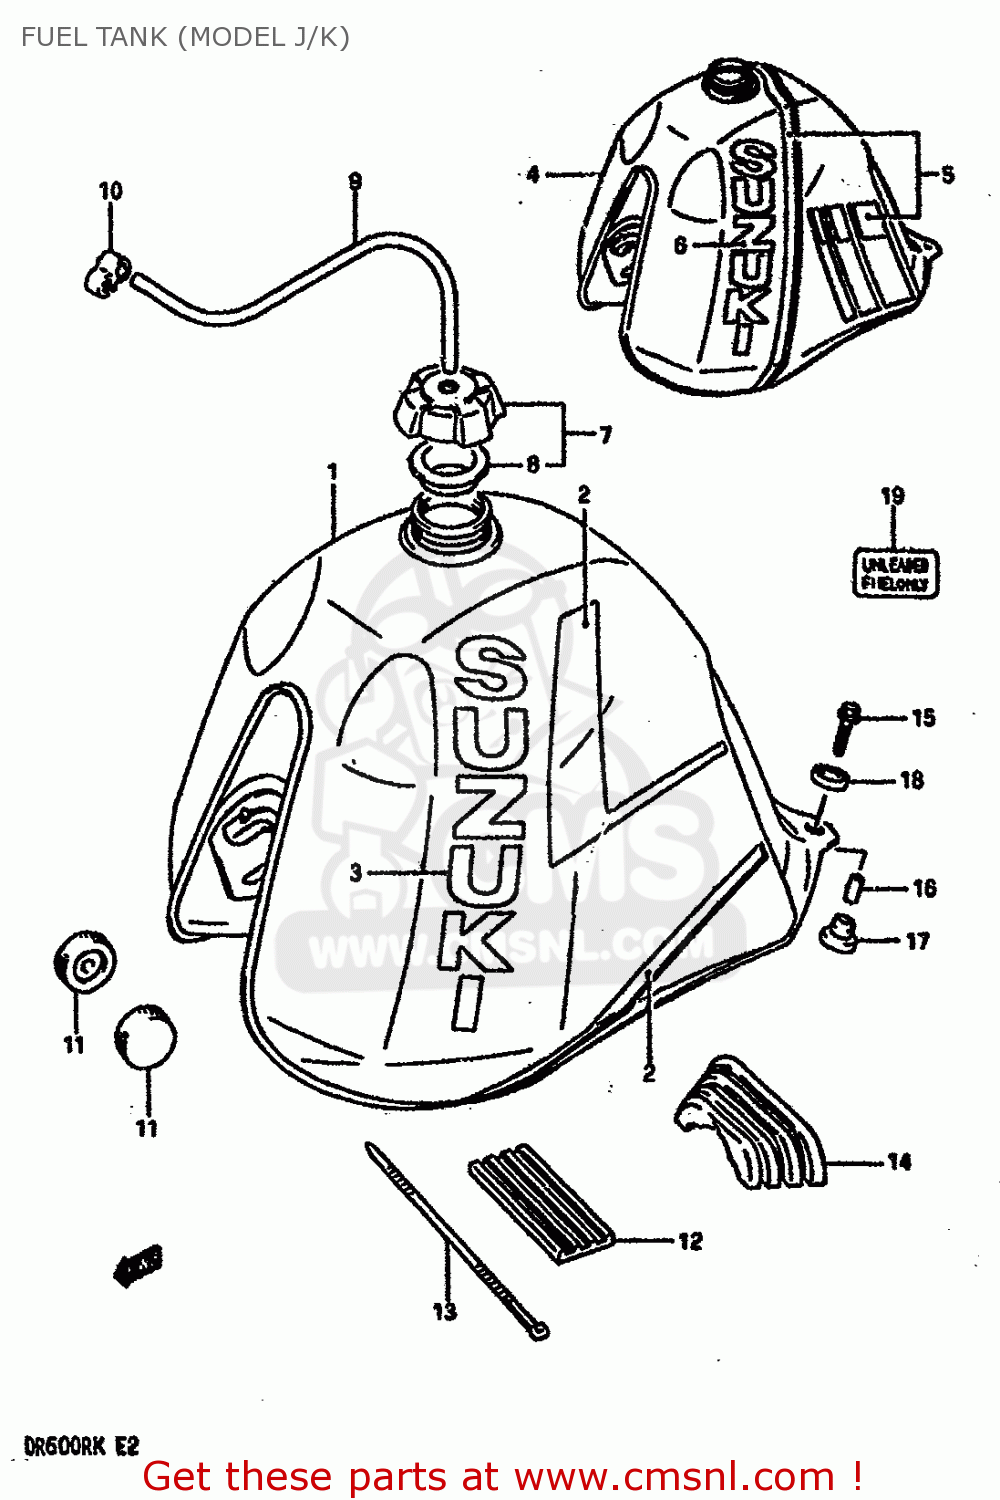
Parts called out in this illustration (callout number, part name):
1	TANK ASSY,FUEL
2	TAPE SET,FUEL TANK
3	EMBLEM SET, FUEL TANK
4	TANK ASSY,FUEL
5	TAPE SET,FUEL TANK
6	EMBLEM,FUEL TANK
7	CAP SET,FUEL TANK
8	GASKET,FUEL TANK CAP (NAS)
9	HOSE
10	CLAMP,FUEL TANK BREATHER HOSE
11	CUSHION
12	CUSHION,FUEL TANK UPR FR
13	CLAMP
14	CUSHION,FUEL TANK RR
15	BOLT
16	SPACER
17	CUSHION
18	CUSHION
19	LABEL,FUEL CAUTION
20	LABEL,FUEL CAUTION
